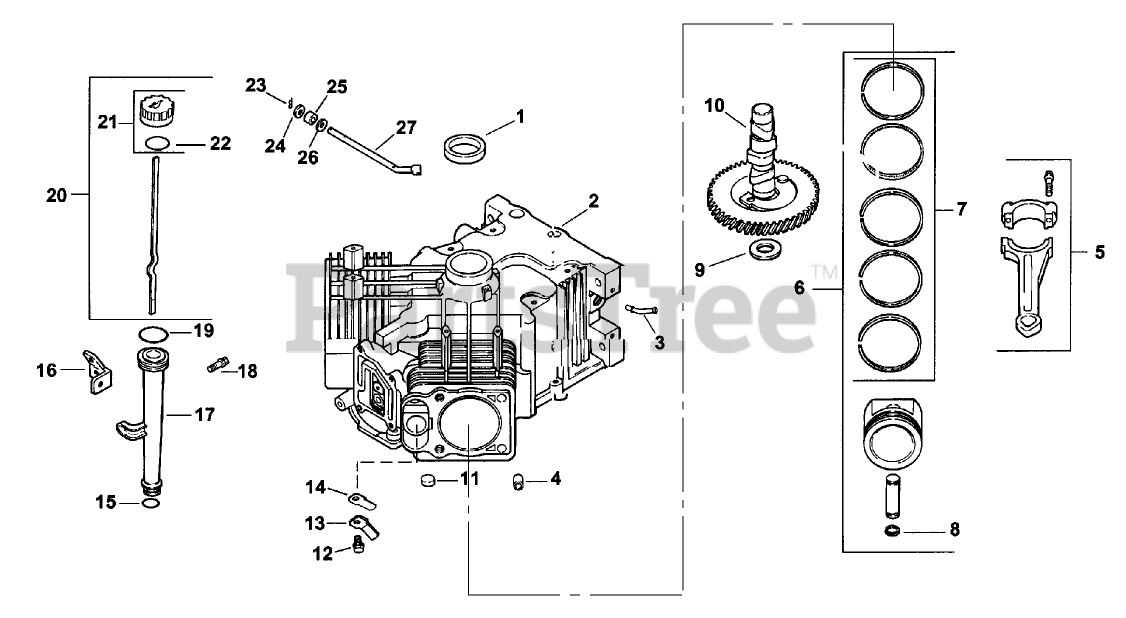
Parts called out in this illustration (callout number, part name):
1	Seal-Oil
2	Miniblock
3	Fitting
4	Dowel-Locating
5	Rod-Connecting (Standard)
6	Piston w/Ring SetStd. (Includes 7-8)
7	Ring Set(Std.)
8	Retainer-Piston Pin
9	Shim-Camshaft
10	Camshaft
11	Plug
12	Screw
13	Retainer-Reed
14	Beed-Breather
15	"O"Ring
16	Bracket-Oil Tube
17	Tube-Oil Fill
18	Screw-HF
19	"O"Ring
20	Dipstick assembly (Includes 21,22)
21	Kit, oil fill cap (Includes 22)
22	"O"Ring
23	Pin-Hitch
24	Washer
25	Seal-Cross Shaft
26	Washer
27	Shaft-Governor Cross
